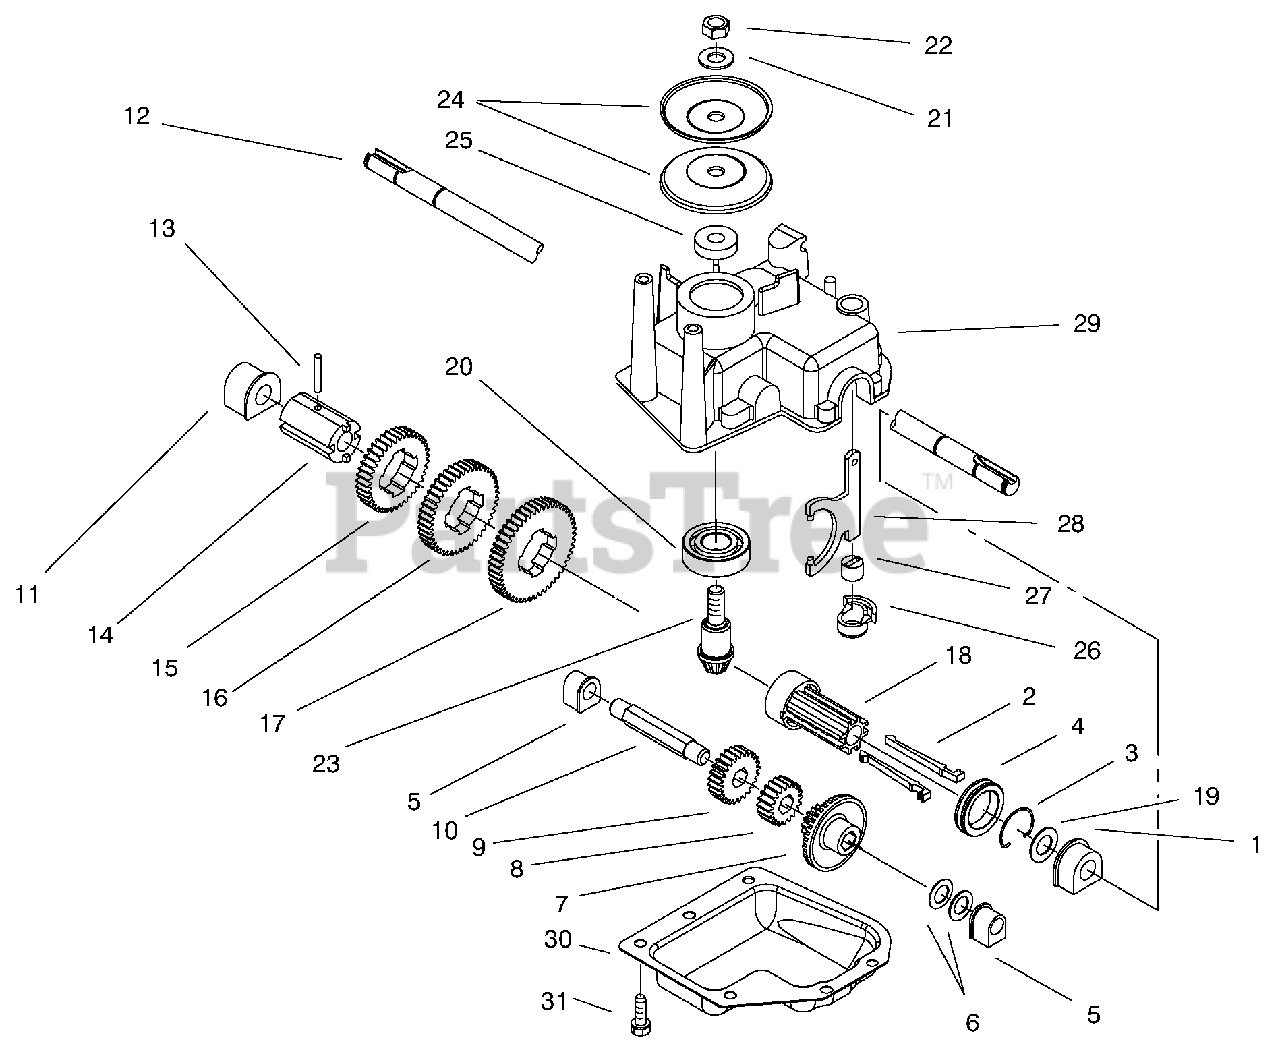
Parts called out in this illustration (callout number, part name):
1	Bushing-Output Shaft
2	Key-Shift
3	Clip-Spring
4	Collar-Shift
6	Washer-Thrust
7	15 T Pinion
8	Pinion 20t 2nd Gear
9	Pinion 25t 3rd Gear
10	Shaft-Intermediate
11	Bushing-Output
12	Shaft-Output
13	Pin-Spirol
14	Sleeve-Gear
15	Gear 39t 3rd Gear
16	Gear 44t 2nd Gear
17	Gear 49t 1st Gear
18	Sleeve-Shift Key
19	Washer-Thrust
20	Bearing-Ball
21	Washer-Flat
22	Nut-Lock
23	Pinion-Bevel
24	Pulley-Half
25	Spacer-Pulley
26	Retainer-Shift-Fork
27	Bushing-Yoke
28	Yoke-Shift
29	Gearcase-Upper 3 Sp
30	Cover-Gearcase
31	Screw-HH
